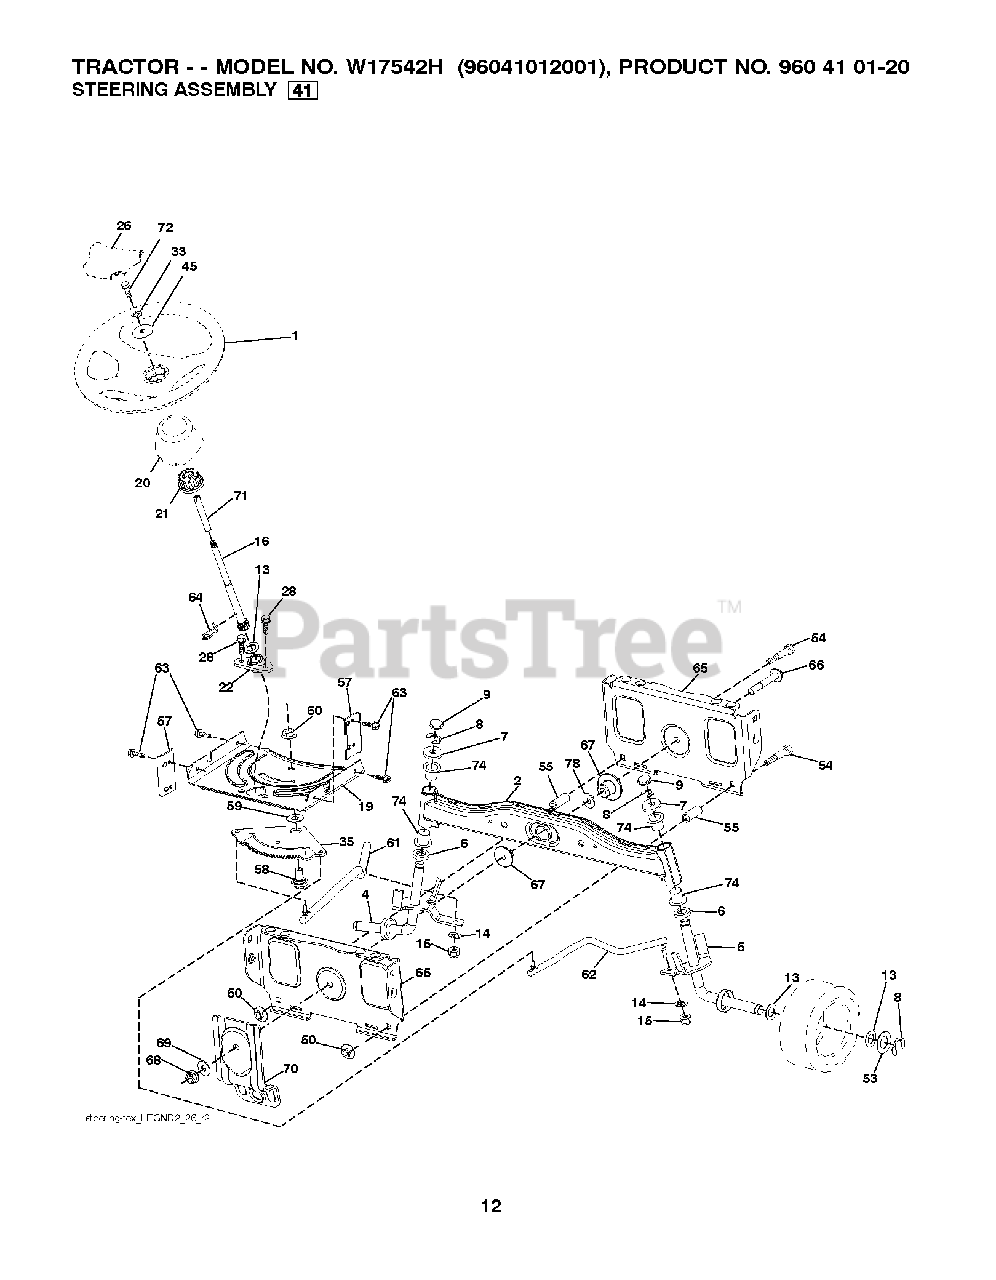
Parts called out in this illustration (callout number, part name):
1	WHEEL.STEERING.STDSRR.BLK/OV
2	AXLE HALF ASM-WELDED
4	SPINDLE.WELDED.LH.15"TEX
5	SPINDLE.WELDED.RH.15"T
8	RING CLIP
9	CAP.SPINDLE.BLACK
14	WASHER, LOCK 3/8
15	NUT CROWNLOCK 3/8-24
16	SHAFT.STEER.3/4.PLATED.TEX
19	PLATE.STEER.DDL.NLT/NG
20	BOOT STEERING BLACK
21	ADAPTER, WHEEL STNG..
22	BUSHING.ASM.STEERING.A
26	INSERT, WHEEL STEERING
28	SCREW, 3/8-16X3/4
33	LOCKWASHER
35	GEAR.SECTOR.PLATE.DDL.
45	WASHER.11/32
50	NUT LOCK FLG 3/8-16 UNC
53	WASHER.HARDENED
55	SPACER.BRACE.AXLE
57	BRACKET.UPSTOP.TEX
58	BOLT.SHOULDER.SECTOR.P
59	WASHER.THURST.SECTOR.S
60	NUT FLANGE LOCK 5/8-11
61	DRAGLINK.LH.BALLSTUD.D
62	DRAGLINK.RH.BALLSTUD.D
63	SCREW
64	RETAINER.CLIP.SPRING.S
65	BRACE.AXLE.FRONT.NLT/N
66	BOLT HEX FGHD 7/16-14 X 3 SERR
67	BUSHING.PM.FRONT AXLE
68	NUT.LOCK.FLANGE.7/16
69	WASHER.1.5X.505X.118
70	BRKT.DECK.SUSPENSION.F
71	SHAFT EXTENSION STEERING
72	BOLT 5/16-18 X 4 W/PATCH
74	Steering Column Bearing
78	THRUST WASHER
